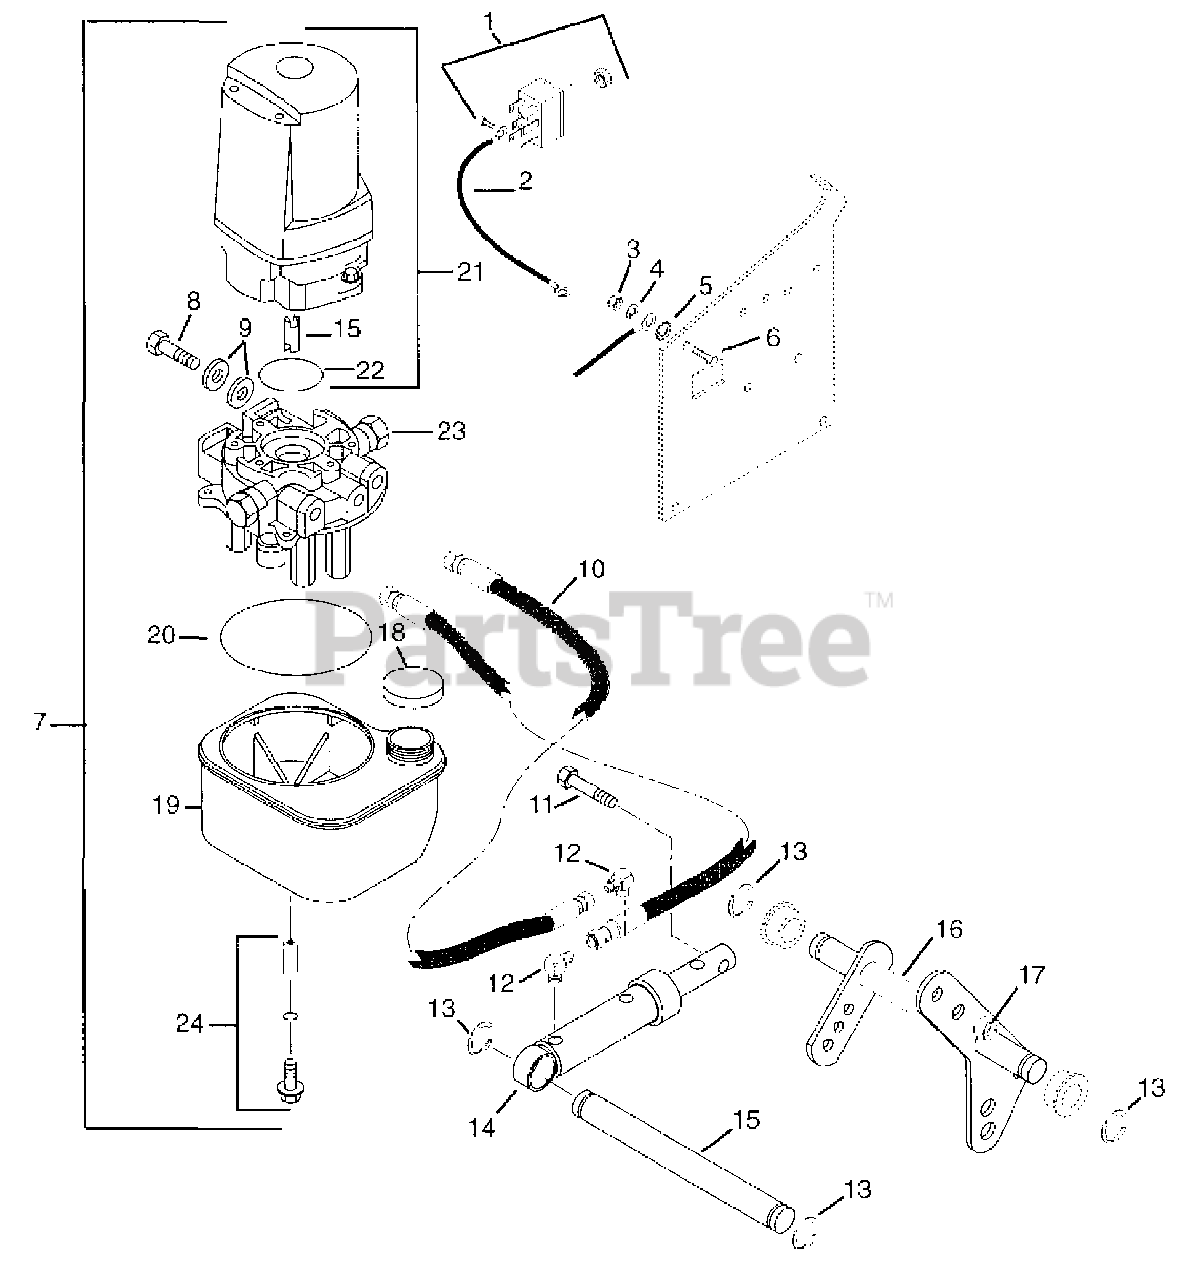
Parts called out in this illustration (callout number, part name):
1	Switch Assembly
2	Power Wire-Deck Lift Pump
3	Nut-Locking-Nylon .312-18 Grade 2
4	Washer-Lock-Internal .31
5	Washer-Flat-Steel .281 x .620 x .065
6	Bolt-Hex .25-20 x .75 Grade 5
7	Pump-Electric Hydraulic
8	Bolt-Hex .38-16 x 1.00
9	Washer-Flat-Steel .390 x .875 x .18
10	Assembly-Hose Pump to Cylinder
11	Bolt-Hex .50-13 x 2.00 Grade 5
13	Ring-Retaining-External .835 x .056
14	Cylinder-Hydraulic
15	Shaft-Hydraulic Cylinder
16	Mower Lift Weldment
17	Nut-Locking .50-13
18	Reservoir Cap-Elec./Hyd. Pump
19	Reservoir Tank
20	Reservoir Seal-O-Ring
21	Motor Assembly
23	Adapter-Assembly
24	Screw O-Ring and Spacer Assembly
